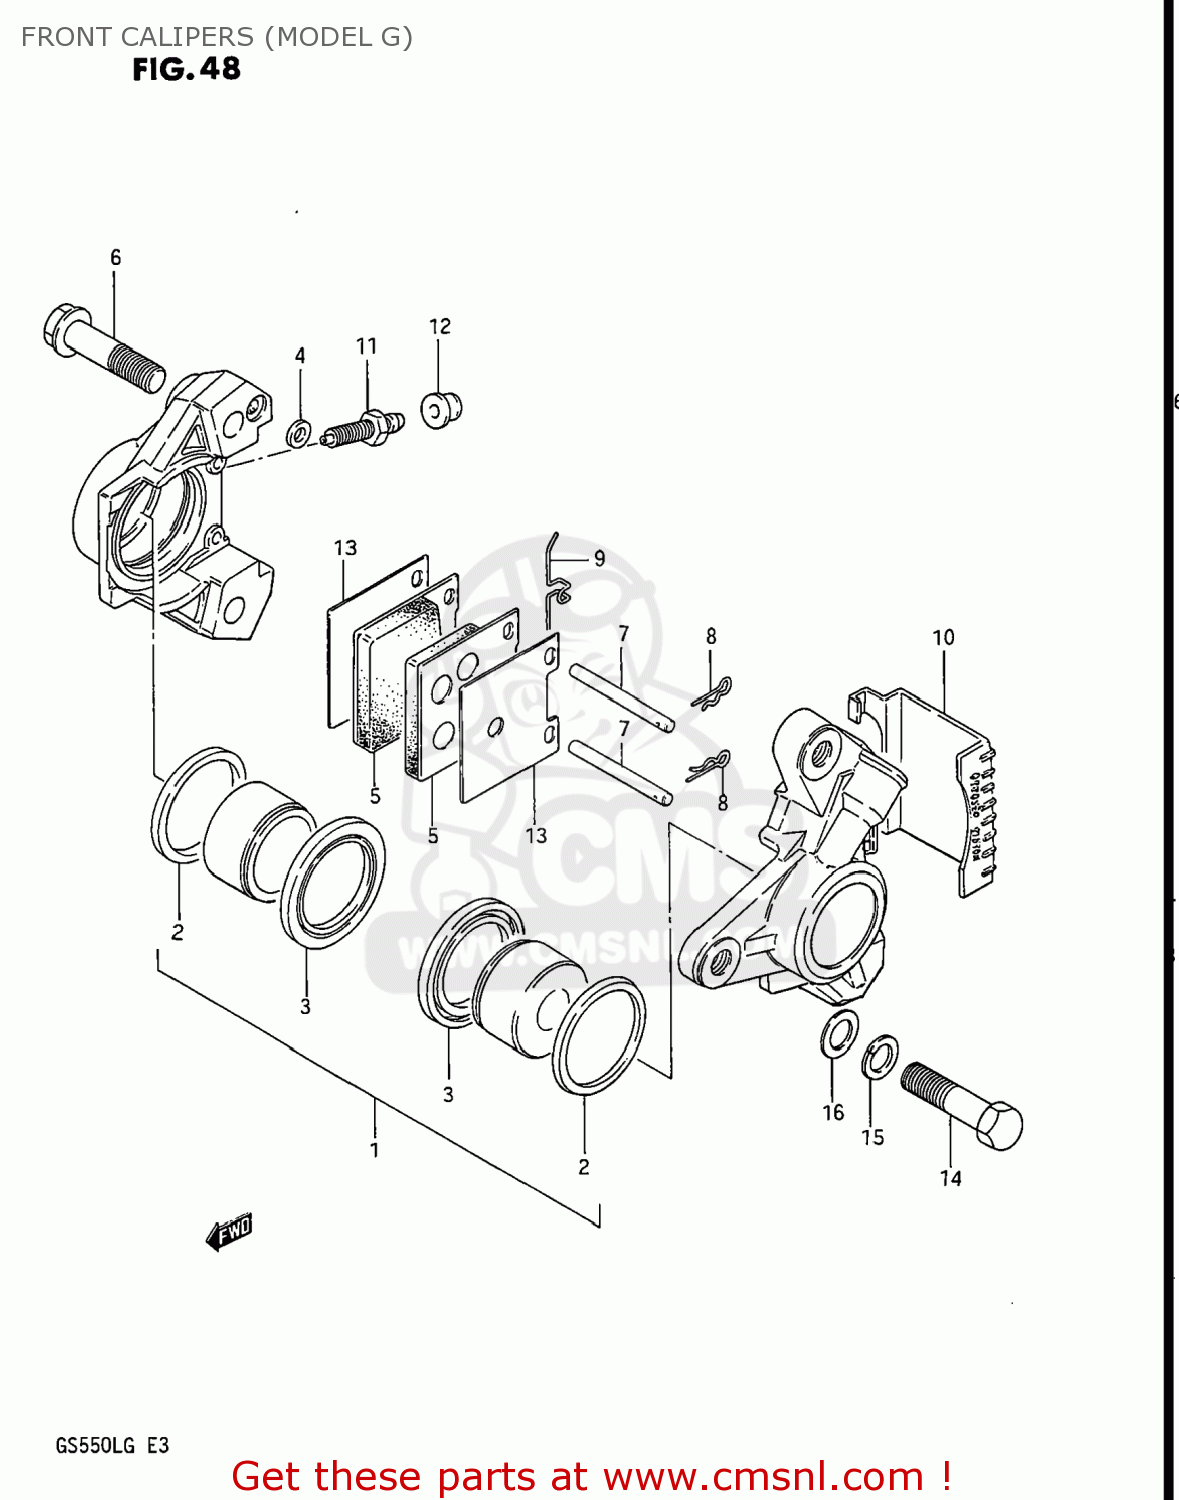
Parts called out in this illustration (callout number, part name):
1	PISTON SET
2	SEAL,PISTON
3	BOOT
4	SEAL,JOINT
5	ASBESTOS !!!
6	BOLT,HOUSING
7	PIN,PAD
8	CLIP,PAD PIN
9	SPRING
10	COVER,CALIPER
11	BLEEDER
12	CAP,BREATHER
13	SHIM,PAD
14	BOLT(10X38)
15	WASHER,LOCK,10
16	WASHER
